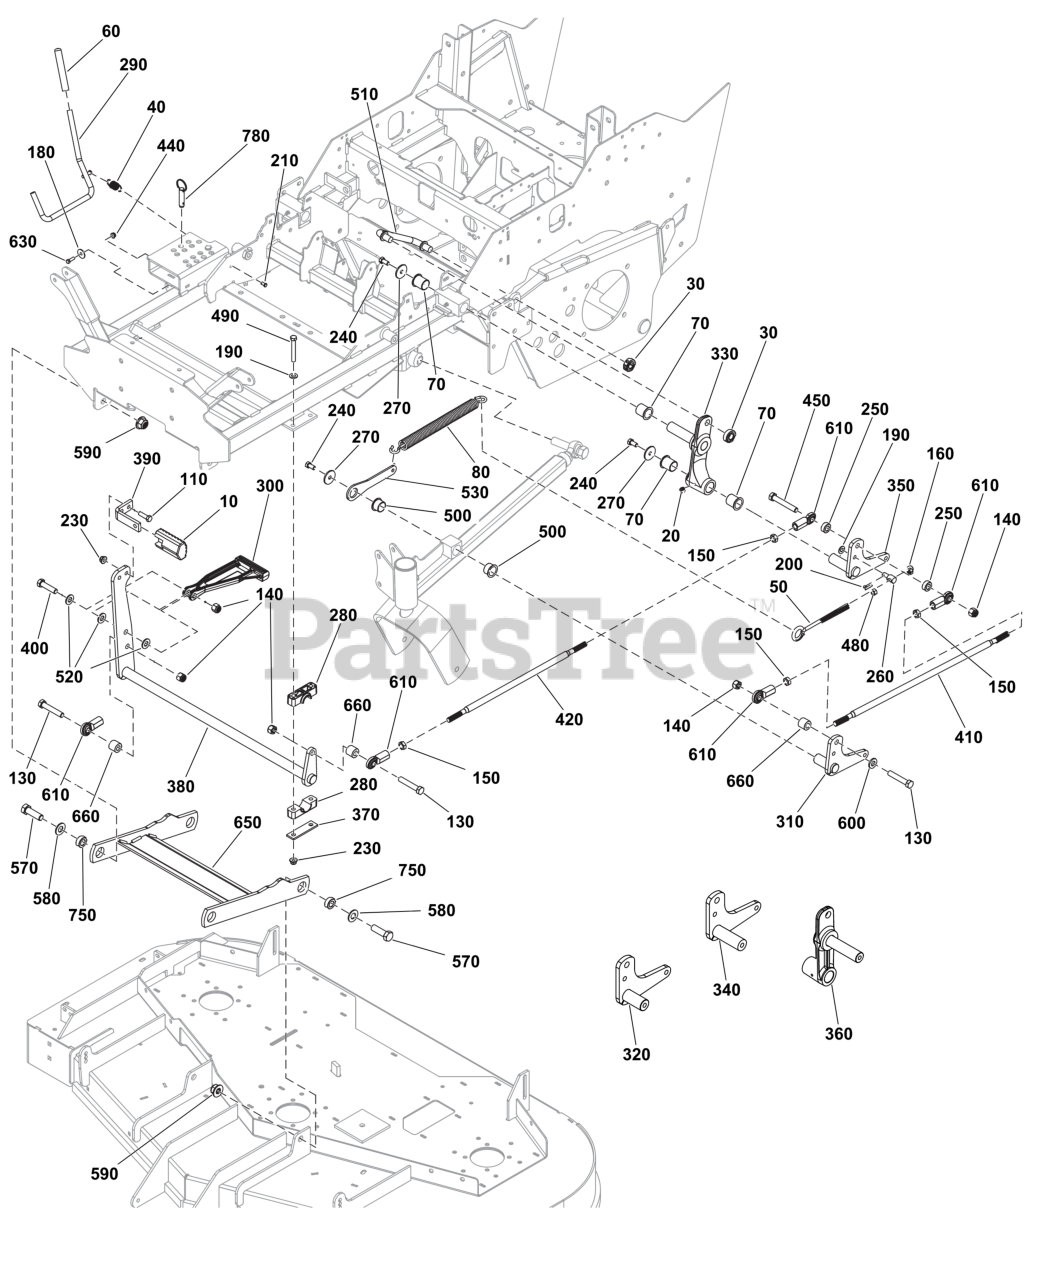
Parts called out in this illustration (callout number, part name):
10	PEDAL, RUBBER
20	GREASE FITTING, 1/4-2
30	COLLAR, 5/8" SPLIT
40	SPRING-EXT, .740 ODX2
50	EYE BOLT, 3/8-16 X 8"
60	GRIP, FOAM
70	BUSHING, 1.00 X 1.13
80	SPRING, DECK LIFT ASS
110	BOLT, 3/8-16 X 1-1/4"
130	BOLT, 1/2-13 X 2-3/4"
150	NUT, 1/2-20 HEX JAM
160	NUT, 3/8-16 HEX NYLON
180	WASHER, 1/4 FENDER
200	PIN - COTTER
210	PIN, CLEVIS, 1/4 X 1/
230	NUT, 3/8-16 HEX NYLOCK
240	BOLT - 3/8-16 X 3/4
250	SPACER, .52 X 1.00 X
260	ADJUSTER - DECK
270	WASHER - .39X1.50
280	PIVOT BLOCK, PLASTIC
290	ROD, Lift
300	ARM-LINK
310	WELD, DECK LIFT LEVER, LH - BLK
320	WELD, DECK LIFT LEVER, RH - BLK
330	ARM, LINK
340	ARM, LINK
350	DECK LIFT LEVER, LH
360	DECK LIFT LEVER, RH
380	WELD, DECK LIFT SHAFT - BLK
390	PEDAL, FOOT
400	BOLT, 1/2-13 X 2 GD5
410	ROD, 1/2-20 X 24.50
420	ROD, DECK LIFT, 19.25
450	BOLT, 1/2-13
480	NUT, 3/8-16 HEX
490	BOLT, 3/8-16 X 2-3/4"
500	BUSHING, 1.00X1.13X.7
510	ROD, SUSPENSION LINK
520	WASHER, 1/2" SAE
530	MOUNT, SPRING, DECK LIFT - BLK
570	BOLT, 5/8-11 X 2
580	WASHER, 5/8" SAE
590	NUT,5/8-11 HEX NYLON
600	WASHER, 1/2" YELLOW
610	JOINT-BALL .500-20 TH
630	BOLT,1/4-20X5/8
650	BAR, Puller
660	SPACER, .52 X 1.00 X
750	BUSHING
780	PIN, HITCH, 1/2 X 2.0
